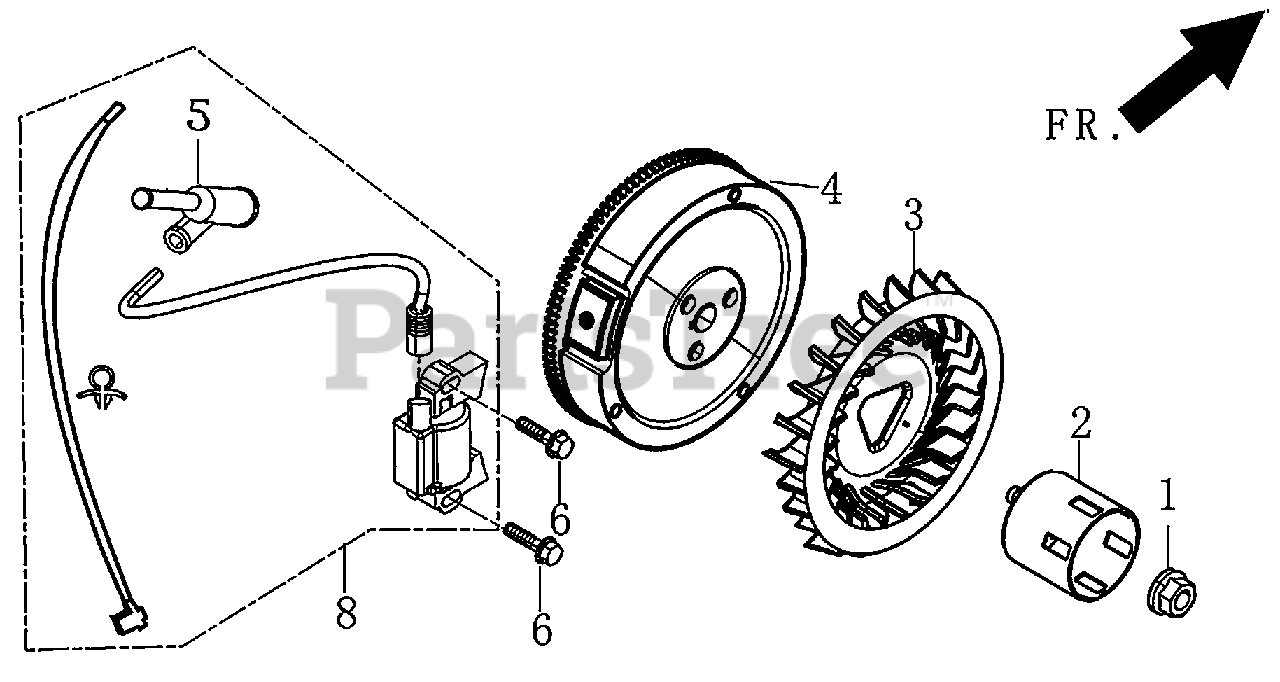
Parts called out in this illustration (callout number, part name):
1	NUT, FLYWHEEL
2	PULLEY,STARTER
3	FAN, COOLING
4	FLYWHEEL ASSY.
5	BOOT, SPARK PLUG
8	COIL, IGNITION
